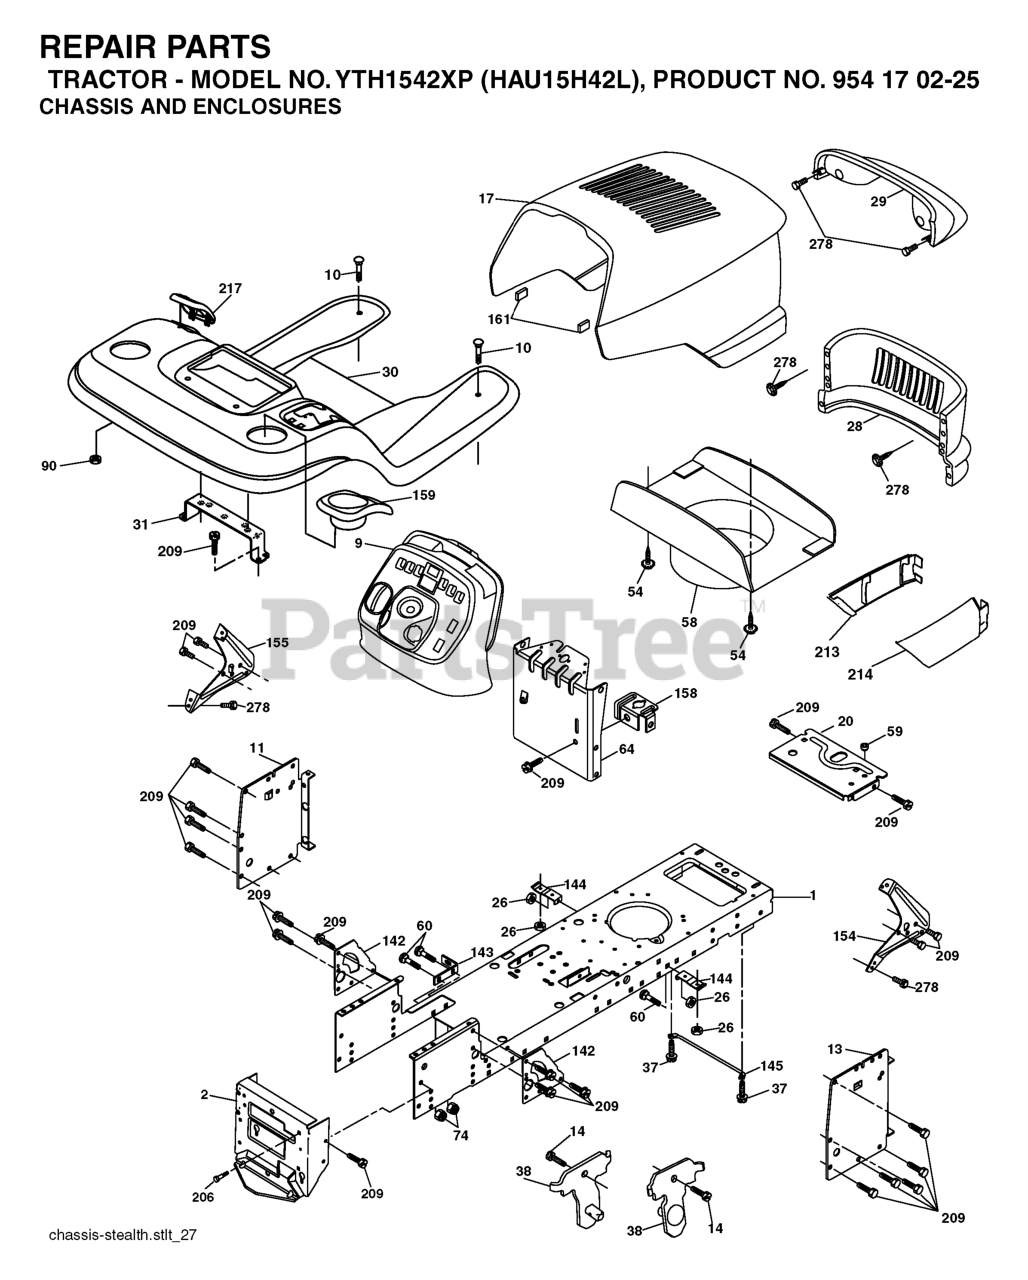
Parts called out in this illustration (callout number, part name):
1	CHASSIS STAMPING
2	DRAWBAR, 12GA
9	DASH
10	BOLT D
11	PANEL DASH LH
13	PANEL DASH RH
17	HOOD
20	PLATE BATTERY
26	NUT
28	GRILLE.STEALTH P/L.YTGT.GREY
29	LIGHTBOX.ASM.STV.DL.INC.HUSQ
30	FENDER STL W/CUPHOLDER
31	BRACKET.SUPPORT.FENDER
37	Screw 5/16-18 x 1/2 Hex, Self Tapping 5/16-18 x 1/2
38	BRACKET.ASM.PIVOT.MOWER.REAR
54	SCREW.HEX.WS.HD.8-18 X 7/8
59	BUSHING.1.375OD
60	Bolt - Rd. Hd. Sq. Neckiage 3/8 16 x 3/4
64	DASH LOWER
90	NUT.PUSH.3/16
142	PLATE REINFORCEMENT
143	BRACKET, SWAYBAR CHASSIS
144	BRKT, FOOT REST
145	ROD PIVOT CHASSIS/HOOD
154	BRACKET DASH STEALTH(R)
155	BRACKET DASH STEALTH LH
158	BRACKET PARKING BRAKE
159	GREY CUP HOLDER
161	EXTRUSION BUMPER (3 2) (2 2)
206	SHOULDER BOLT 5/16-18TT
209	SCREW, 3/8-16X3/4
213	SKIRT GRILLE LH
214	SKIRT GRILLE RH
217	CONSOLE FUEL WINDOW
278	SCREW
